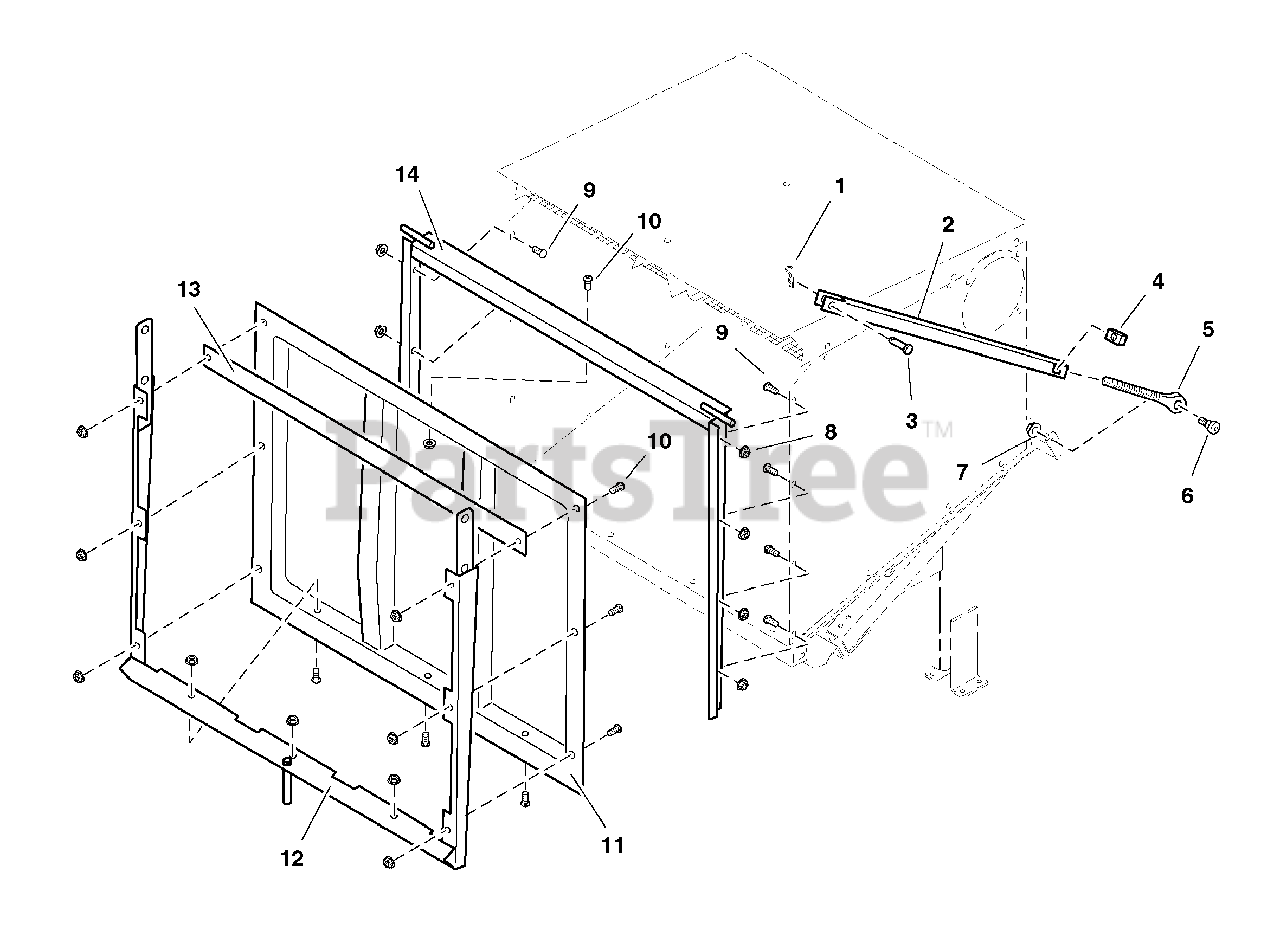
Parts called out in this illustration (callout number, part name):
1	PIN, RUE RING HAIR
2	LINKAGE ROD
3	LINKAGE PIN
4	ADJUSTING NUT
5	ADJUSTING SCREW
6	SHOULDER BOLT, 3/8 x 1/2
7	NUT, 3/8-16 Hex Serrated Flange
8	NUT, Hex, Flange, 1/4-20
9	CARRIAGE BOLT, 1/4-20 x 5/8
10	PHILIPS HEAD PAN SCREW, 1/4-20 x 5/8
11	PLASTIC DOOR
12	DOOR FRAME ASSEMBLY
13	UPPER DOOR MEMBER
14	BOX & DOOR FRAME
